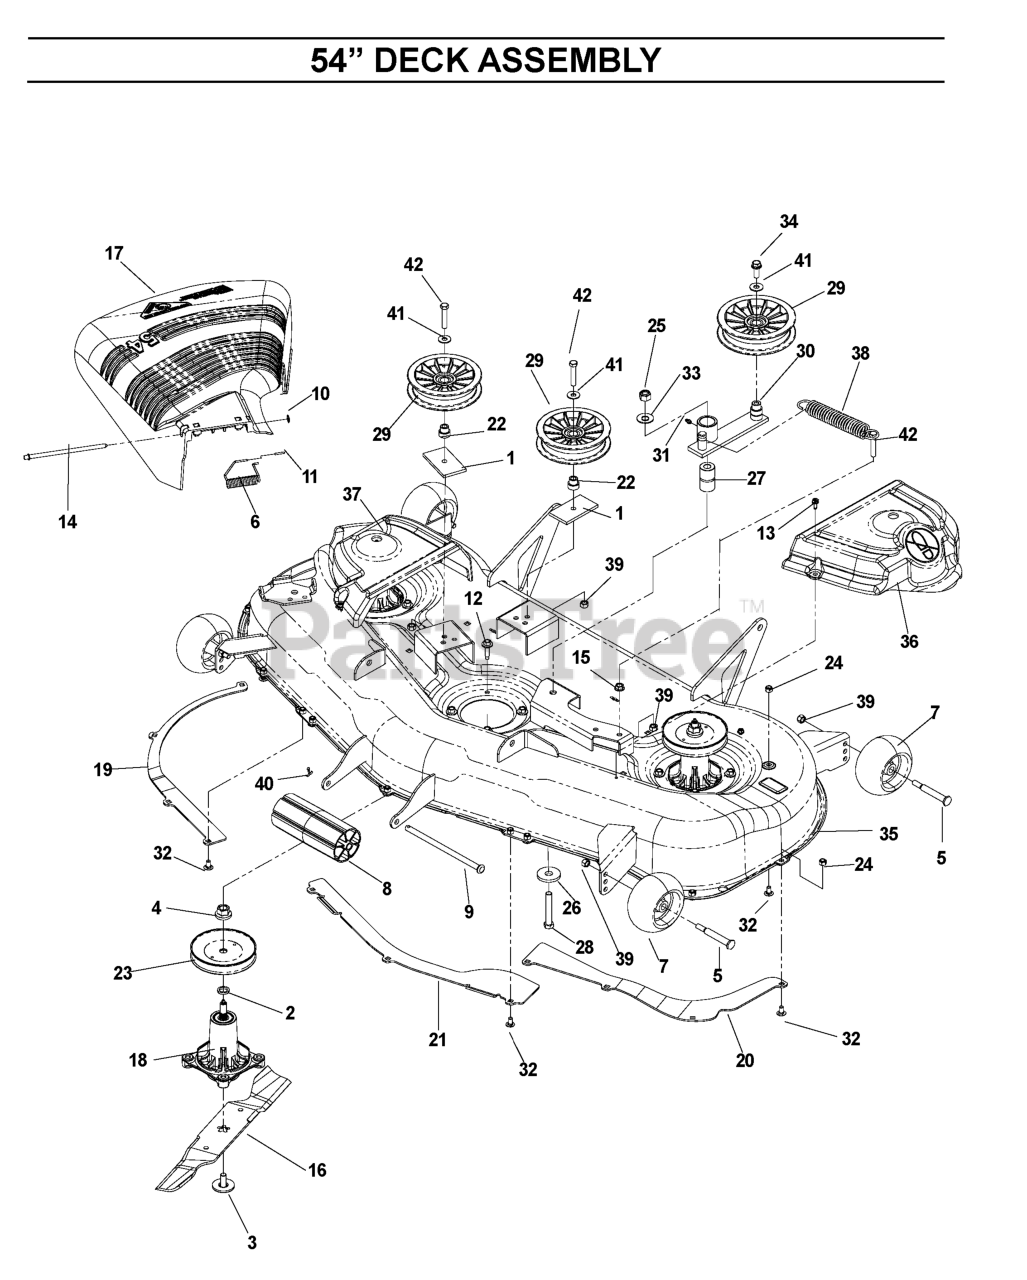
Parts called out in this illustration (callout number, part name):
1	SUPPORT PLATE
2	WASHER-SPACER
3	BOLT 7/16 ASM BLADE
4	LOCKNUT - 9/16
5	BOLT, SHOULDER
6	TORSION SPRING
7	WHEEL GAGE DONUT
8	NOSE ROLLER 48"
9	NOSE ROLLER ROD
10	PUSH NUT
11	CAP-SLEEVE
12	WASHER HEAD SCREW
13	SCREW- 1/4-20 X 5/8
14	ROD.HINGE
15	NUT 3/8C WHIZ
16	48" Hi-lift Blade
17	DEFLECTOR.BLACK.54"
18	RP.MANDREL ASM. SERVICE
19	BAFFLE, RIGHT 54"
20	BAFFLE LEFT 54
21	BAFFLE, CENTER, 54"
22	IDLER BUSHING
23	PULLEY MANDREL
24	NUT 5/16 NYLOC
25	NUT 1/2-13 HEX NYLOC ZD
26	WASHER, SUPPORT
27	PIVOT BUSHING
28	HCS 1/2C X 3 1/4
29	IDLER
31	ZERK
32	CARRIAGE BOLT 5/16C X 5/8"
33	WASHER 1/2 FLAT
34	4CS 3/8C X 1 SERRATED HEAD
35	DECK W/DECALS 54" HUS ORANGE
36	BELT SHIELD, LT
37	BELT SHIELD, RT
39	NUT 3/8-16 NYLOC
40	RP_COTTER PIN 1/8 X 3/4
41	WASHER 3/8 FLAT
42	HCS 3/8C X 2
